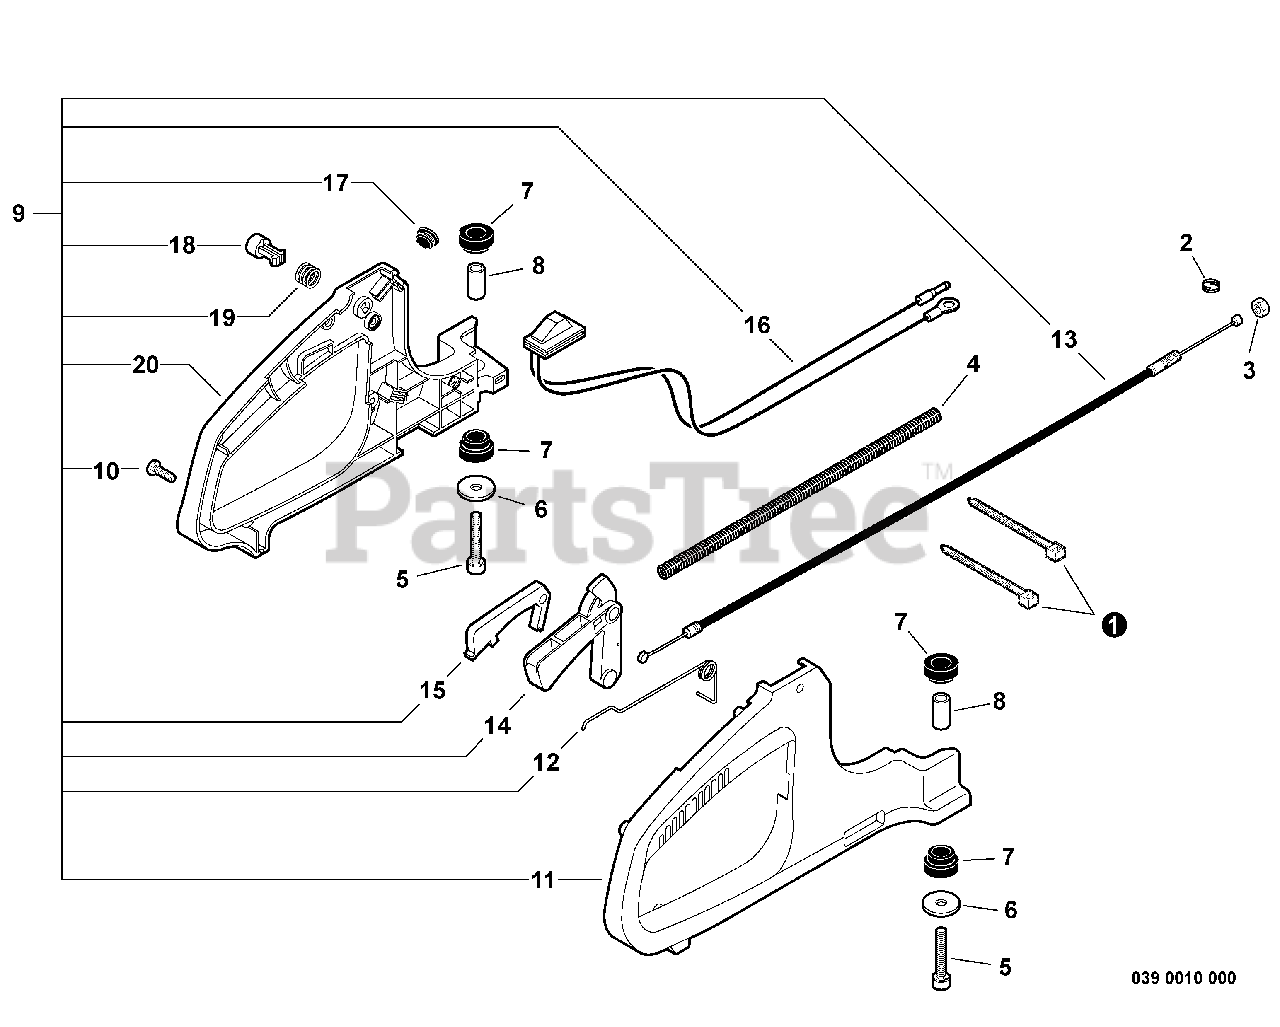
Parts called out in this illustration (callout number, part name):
1	TIE, CABLE
4	TUBE, PROTECTIVE - CORRUGATED
5	SCREW - 6X35
7	CUSHION
9	HANDLE ASSY - REAR
10	SCREW - 4X8 -- TAPPING
11	HANDLE, REAR - RIGHT
12	SPRING, TRIGGER
13	CABLE, THROTTLE
14	TRIGGER, THROTTLE
15	LEVER, TRIGGER LOCKOUT
16	IGNITION SWITCH ASSY
18	LOCK, THROTTLE
20	HANDLE, REAR - LEFT
